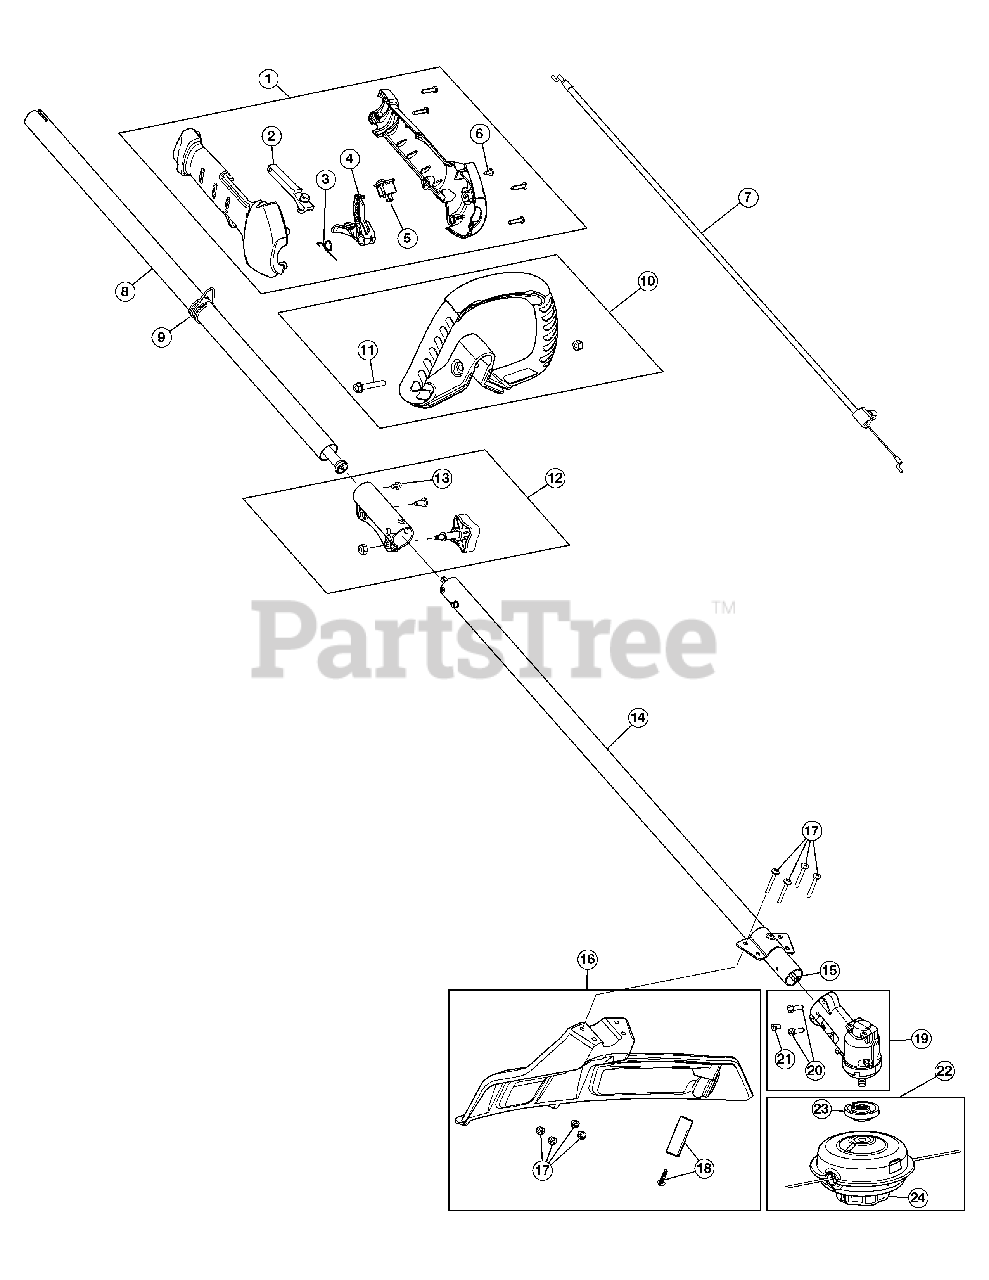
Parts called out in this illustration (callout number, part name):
1	Throttle Housing Assembly (Incl. 2 - 6)
2	Throttle Lockout
3	Throttle Trigger Spring
4	Throttle Trigger
5	Switch Assembly
6	Grip Anti-Rotation Screw
7	Throttle Cable
8	Upper Drive Shaft Housing
9	Shoulder Strap Clip
10	D-Handle Assembly (Incl. 11)
12	Split Boom Coupler (Incl. 13)
13	Coupler Anti-Rotation Screw
14	Lower Drive Shaft Housing Assembly
15	Lower Flexible Drive Shaft
16	Shield Assembly (Incl. 17 & 18)
17	Shield Mounting Screws and Nuts
18	Blade Assembly
19	Gearbox Assembly (Incl. 20 - 24)
20	Gearbox Mounting Hardware
21	Anti-Rotation Screw
22	Cutting Head Assembly
23	Cutting Head Driver
